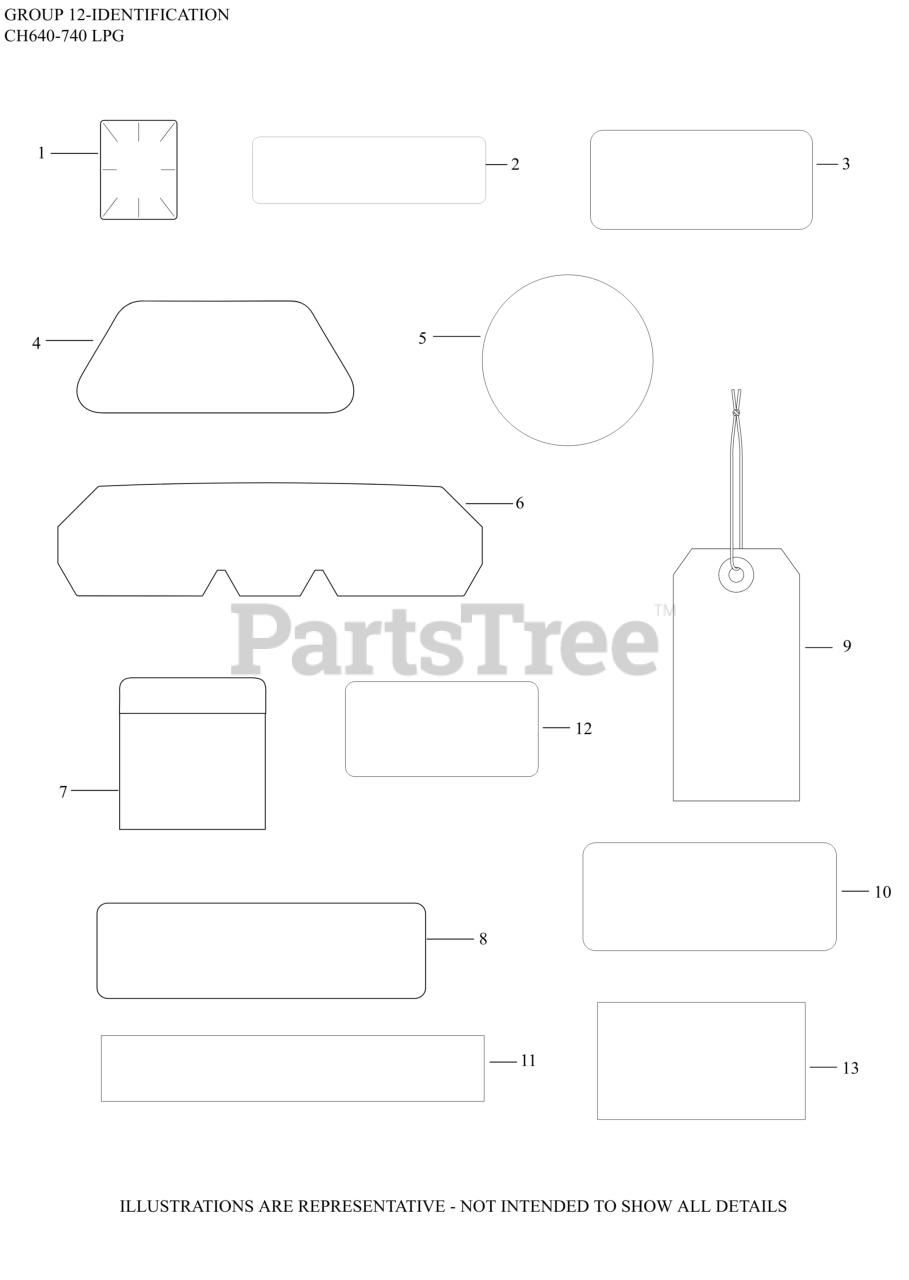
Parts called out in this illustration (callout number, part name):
1	LABEL, CLEAR LAMINATION
7	DECAL, CO WARNING
8	DECAL LPAC, PROPANE/NG
